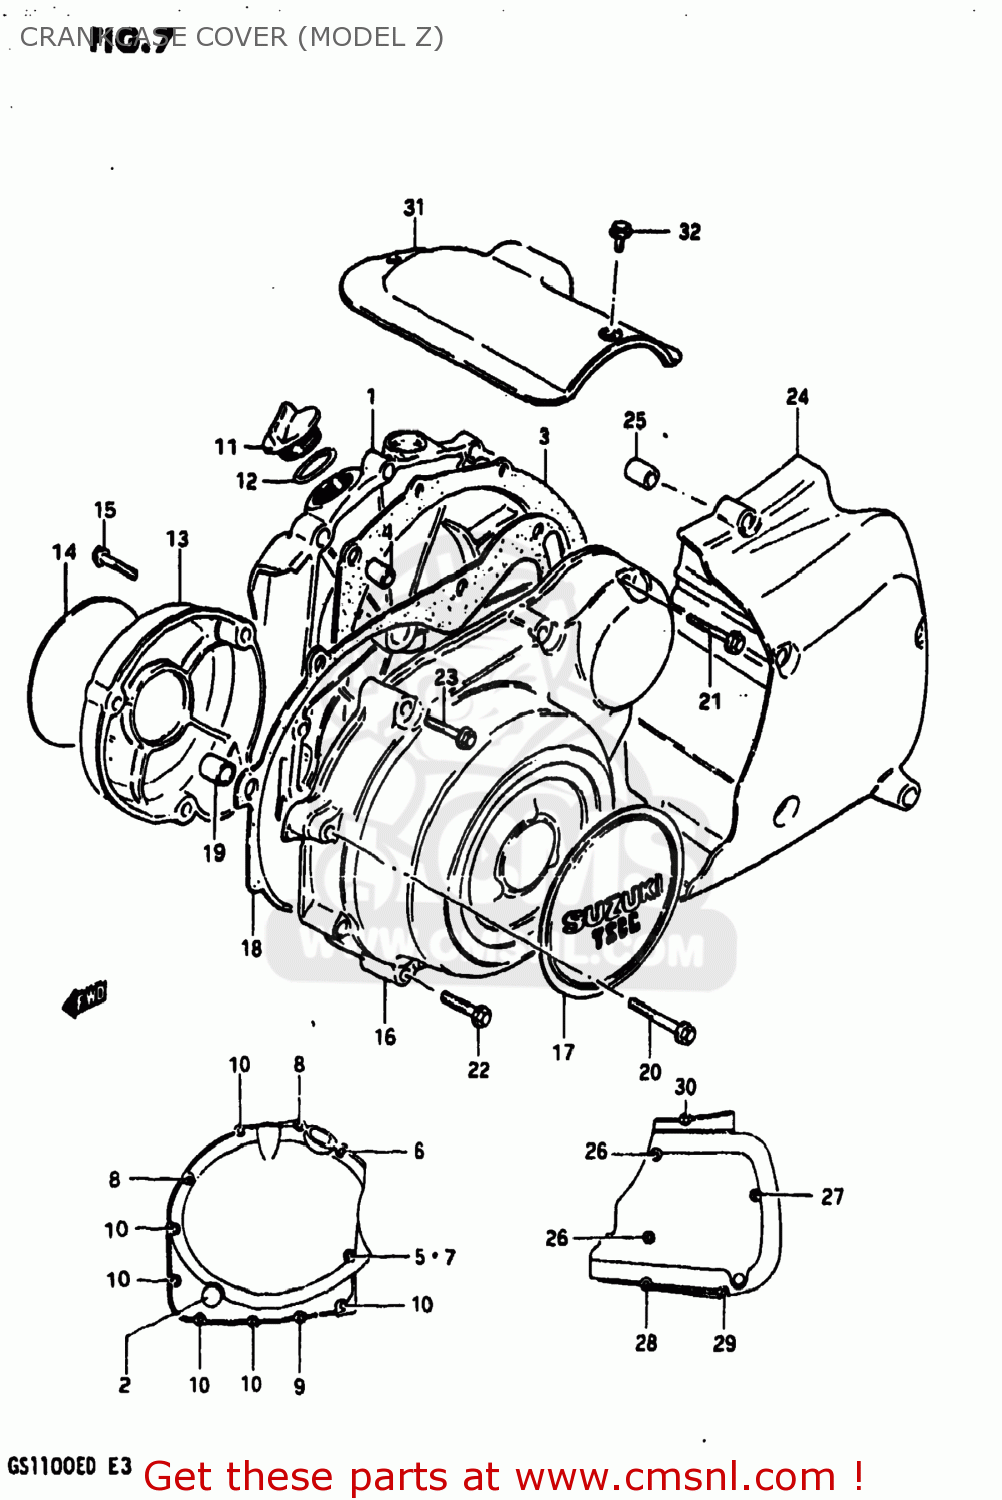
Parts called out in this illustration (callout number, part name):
1	COVER,CLUTCH
2	LENS,OIL LEVEL CHECK
3	GASKET,CLUTCH COVER (MCA)
4	PIN
5	GASKET (NAS)
6	BOLT (6X40)
7	BOLT (6X35)
8	BOLT (6X30)
9	BOLT
10	BOLT (6X20)
11	CAP
12	O RING(D:2.2,ID:32)
13	COVER,CONTACT BREAKER
14	EMBLEM
15	BOLT (5X30)
16	COVER,MAGNETO
17	EMBLEM,MAGNETO COVER
18	GASKET,MAGNETO COVER (MCA)
19	PIN
20	BOLT
21	BOLT (6X40)
22	BOLT (6X35)
23	BOLT (6X30)
24	COVER,ENGINE SPROCKET
25	PIN
26	BOLT 6X95
27	BOLT (6X85)
28	BOLT (6X70)
29	BOLT (6X55)
30	BOLT (6X30)
31	COVER,STARTER MOTOR
32	BOLT
